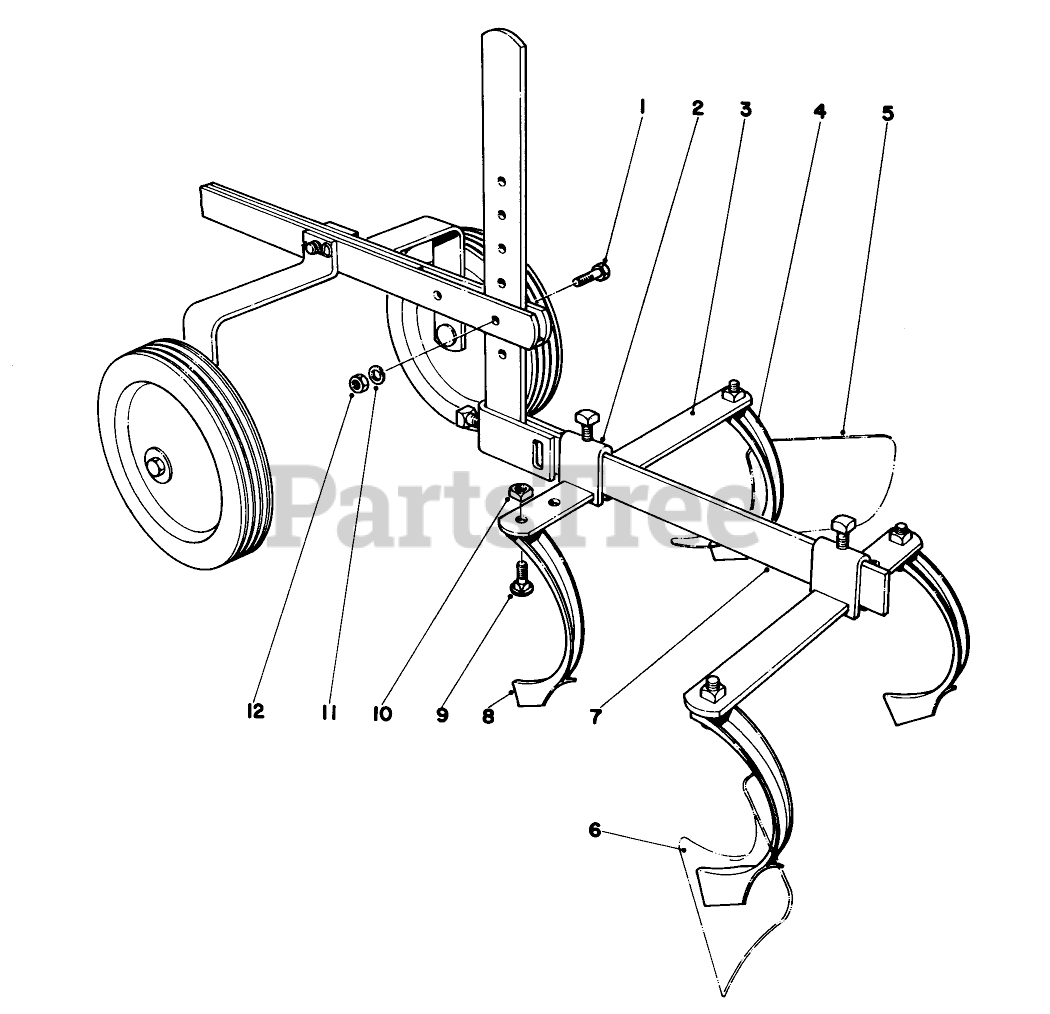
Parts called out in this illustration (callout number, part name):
1	SCREW-HH
2	Clamp
3	Tool Bar
4	Tool Shank
5	Hilling Shovel
6	Hilling Shovel
7	Pull Bar Assembly
8	Cultivator Tooth
9	SCREW-CARR
10	NUT-HEX
11	WASHER-LOCK
12	NUT-HEX
